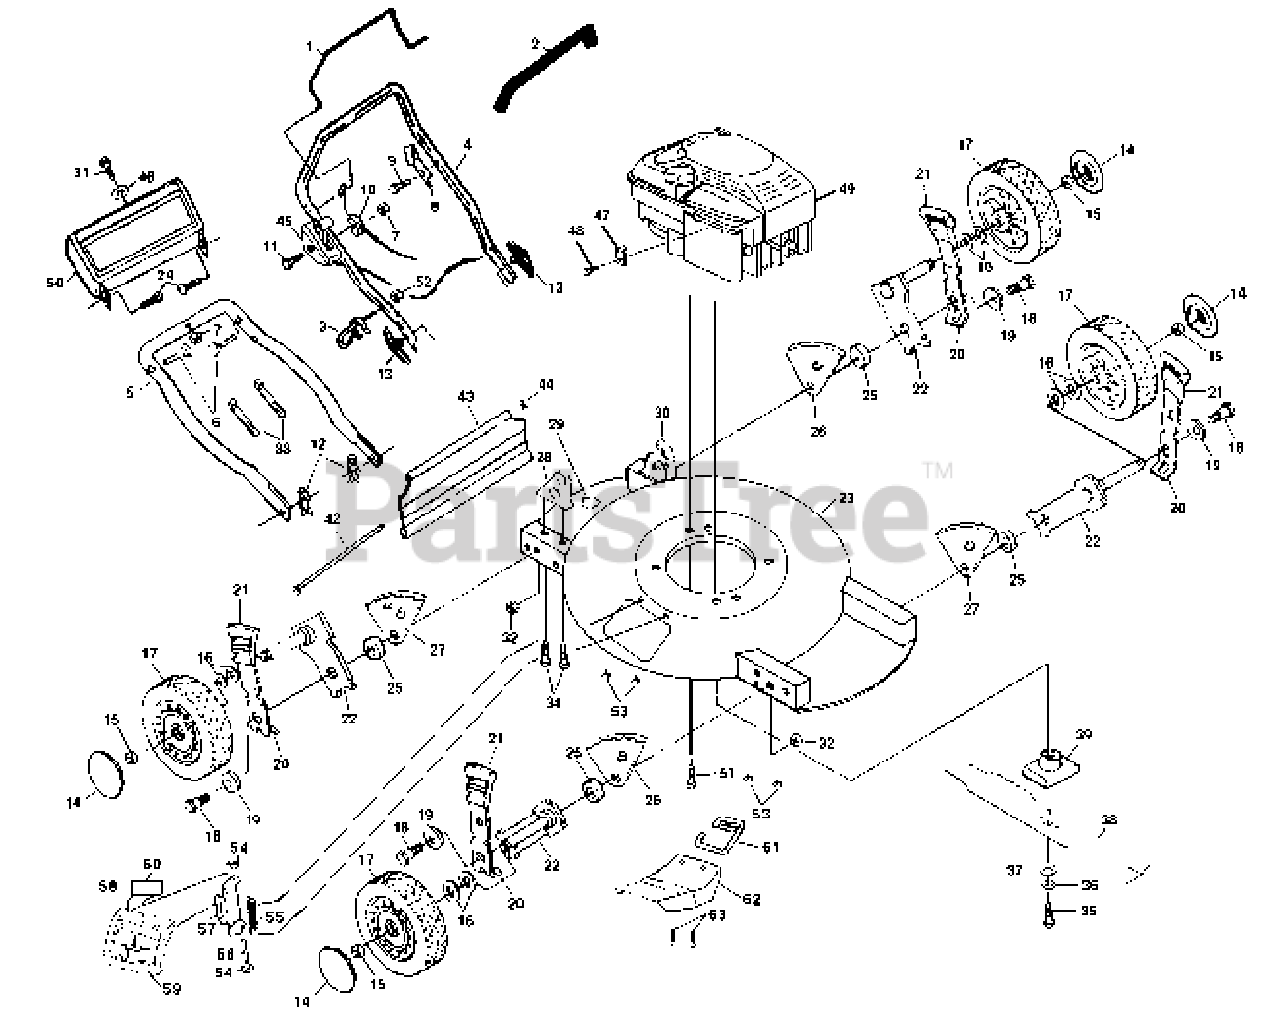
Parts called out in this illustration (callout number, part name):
1	Control Bar
2	Handle Grip
3	Rope Guide
4	Upper Handle
5	Lower Handle
6	Handle Bolt 5/16-18 x 1-3/4
7	Locknut 1/4-20
8	Up-Stop Bracket
9	Hex Washer Head Screw #10-24 x 1/2
10	Engine Zone Control Cable
11	Hex Washer Head Screw 1/4-20 x 2.12
12	Hairpin Cotter
13	Handle Knob
15	Hex Locknut 3/8-16
16	Washer
17	Wheel & Tire Assembly
18	Shoulder Bolt
19	Belleville Washer
20	Selector Spring
21	Selector Knob
22	Axle Arm Assembly
23	Lawn Mower Housing
25	Spacer
26	Wheel Adjusting Bracket (R.F./L.R.)
27	Wheel Adjusting Bracket (L.F./R.R.)
28	Handle Bracket Assembly (Right)
29	Danger Decal
30	Handle Bracket Assembly (Left)
31	Screw
32	Locknut 3/8-16
33	Wire Tie
34	Thread Cutting Screw 5/16-18 x 3/4
35	Hex Head Screw 3/8-24 x 1-3/8
36	Helical Lockwasher 3/8
37	Hardened Washer
38	20" Blade
39	Blade Adapter
42	Deflector Rod
43	Rear Deflector
44	Retainer Clip
45	Throttle Control
47	Cable Clamp
48	Thread Rolling Screw #10-32 x 5/8
50	Trim Plate
51	Hex Head Screw, Self Tap. 3/8 - 16 x 1.1
52	Keps Locknut 1/4-20
53	Locknut
54	External E-Ring
55	Torsion Spring
57	Housing Assembly Bracket
58	Mulcher Door
59	Door Latch
61	Chute Mounting Bracket
62	Mulcher Deflector
63	Truss Head Screw
